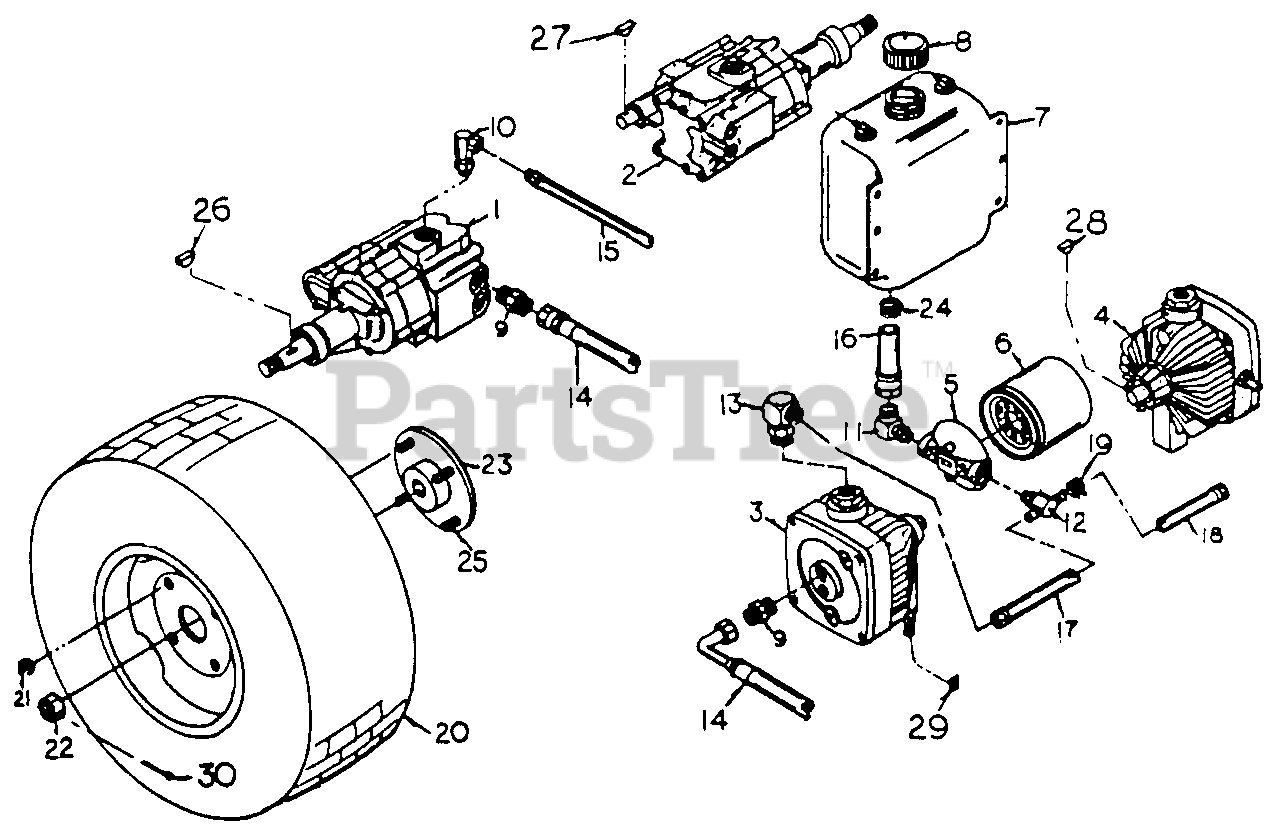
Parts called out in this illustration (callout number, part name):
1	Wheel Motor, LH
2	Wheel Motor, RH
3	Pump, LH
4	Pump, RH
5	Housing, 0i1 Filter
6	Element, 0i1 Filter
7	3 Qt. 0i1 Tank
9	Male Tube, Male O-ring Adp.
10	Male O-ring, 90ø Female-Pipe Swivel Adp.
11	Male O-rlng, 90ø Tube Adp.
12	Male 1-O-ring, 1/2" Hose Barb Tee
13	Male O-ring, 90-Male Tub Atp.
14	Hose, 112" lD 28" Long
15	Hose, 1/4" ID 24" Long, Easy Couple
16	Hose, 5/8" ID 3 3/4" Long, Easy Couple
17	Hose, 1/2" ID 7 3/4" Long, Easy Couple
18	Hose, 1/2" ID x 12" Long, Easy Couple
19	Hose Clamp, 1/2"
20	Wheel Ass'y. 18 x 9. 50-8
21	Lug Nut, 1/2-20
22	Nut, Wheel Motor
23	4-Bolt Whe-l Hub
24	Hose Clamp, 5/8"
25	Lug Bolt, 1/2-20 x 1 1/4"
26	Woodruff Key, 1/4" x 1"
27	Woodruff Key, 3/16" x 3/4"
28	Woodruff Key, 1/8" x 1/2"
29	Woodruff Key, 1/8" x 3/8"
30	Cotter Pln, 1/8" x 1 3/4"
